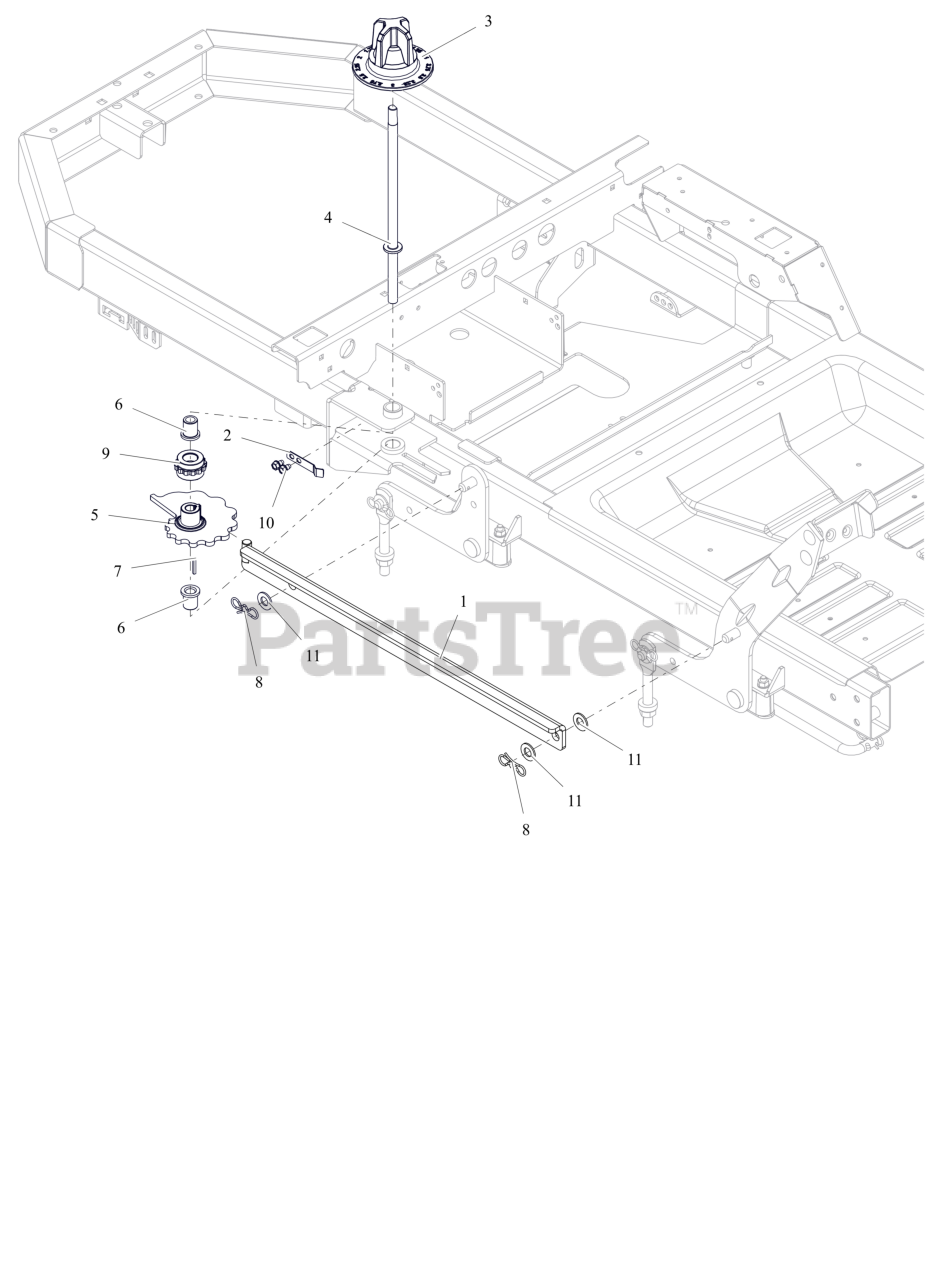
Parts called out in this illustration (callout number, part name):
1	WLDMT, HOC LINK
2	ARM, HOC DETENT
3	KNOB, HOC DIAL
4	SHAFT, CAM
5	CAM, HOC (PM)
6	BSHG-FLG, .503X.750X.875X1.00
7	KEY, 1/8 X 1/8 X 1.0
8	PIN, BOWTIE .091X1.875 ZCC
9	GEAR, HOC INDEX
10	SCR,TAP .25-20X.375 HWH TR ZCC
11	WSHR-FL-NYL .518X1.000X.080
